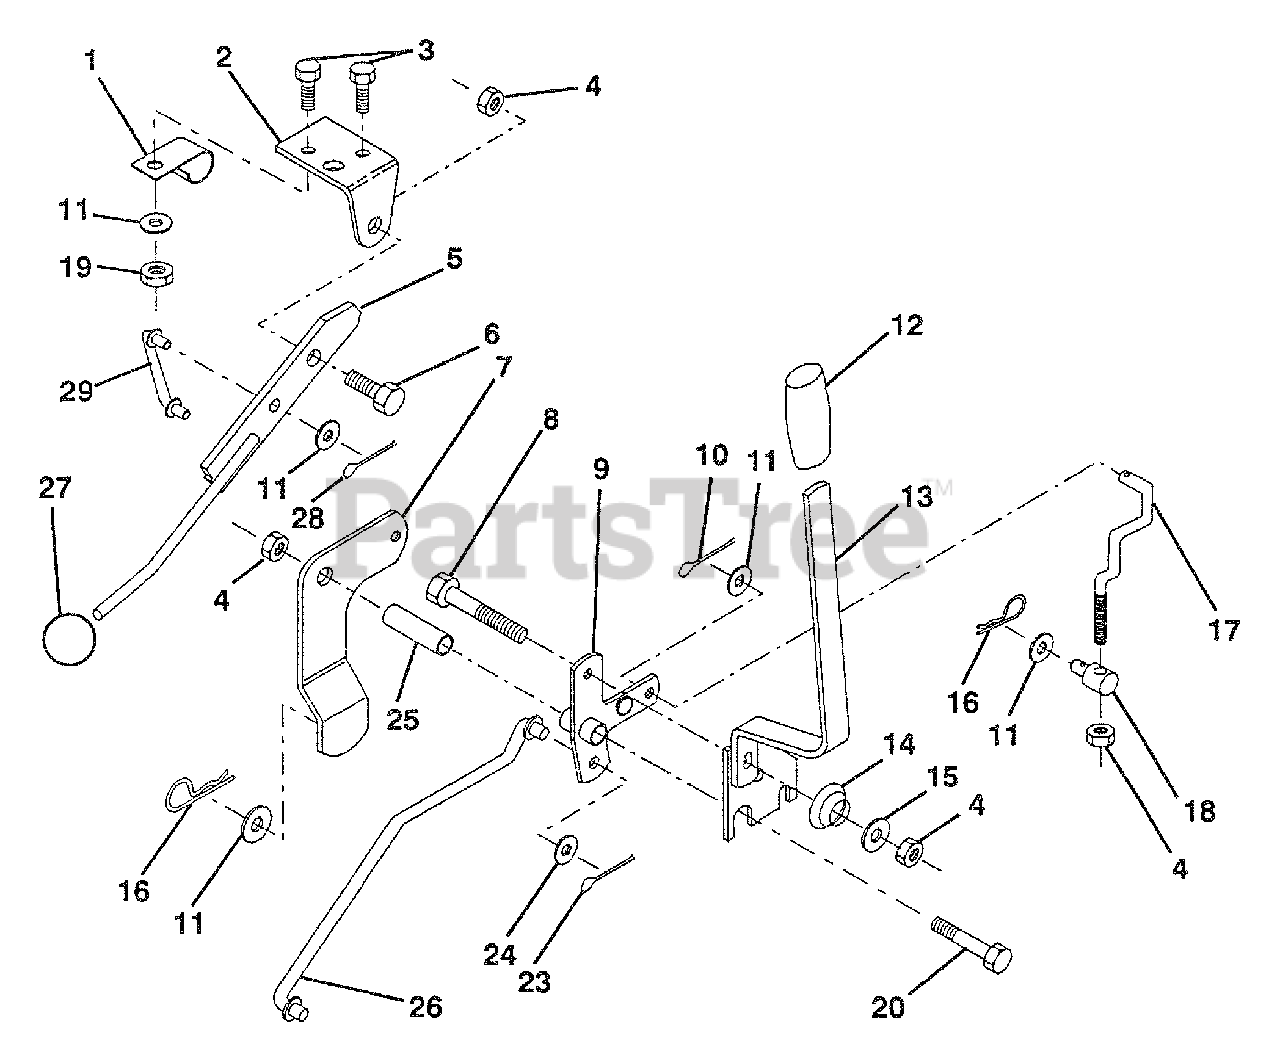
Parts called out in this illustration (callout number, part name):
1	Clip, Insulated
2	Bracket, Mower Clutch
3	Bolt, Fin. Hex 1/4-20 UNC x 1/2 Gr. 5
4	Nut, Crownlock 3/8-16 UNC
5	Assembly, Clutch Lever
6	Bolt, Shoulder
7	Assembly, Mower Clutch Arm
8	Bolt, Hex 3/8-16 UNC x 2-1/4
9	Assembly, Bracket Lift
10	Pin, Cotter 1/8 x 3/4
11	Washer 13/32 x 13/16 x 16 Ga.
12	Grip, Handle
13	Assembly, Lift Handle
14	Spring, Compression
15	Washer 13/32 x 3/4 x 12 Ga.
16	Retainer, Spring
17	Link, Front Lift
18	Trunnion, Threaded 3/8-16
19	Nut, Crownlock 1/4-20
20	Bolt, Fin. Hex 3/8-16 UNC x 2-3/4
23	Pin, Cotter 1/8 x 1
24	Washer 17/32 x 1 x 16 Ga.
25	Tube,Spacer
26	Rod, Mower Lift
28	Pin, Cotter 3/32 x 3/4
29	Link, Mower Clutch
